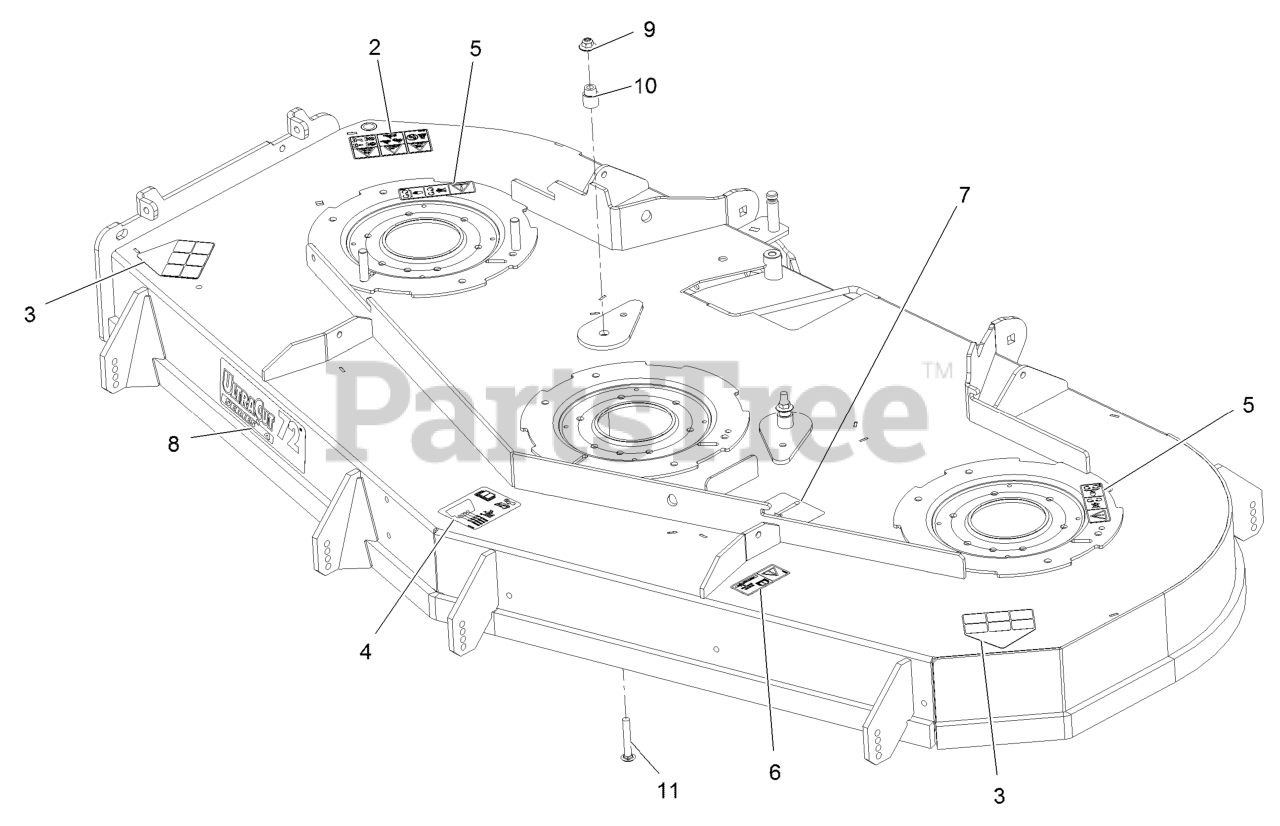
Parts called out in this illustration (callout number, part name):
2	DECAL-DANGER
3	DECAL-DANGER
4	DECAL-ROLLER, ANTI-SCALP
5	DECAL-COVER, MISSING
6	DECAL-BOLT TORQUE
7	DECAL-BELT ROUTING
8	DECAL,ULTRACUT 72 SERIES
9	Nut-Nyloc 3/8-16 Flg
10	BUSHING-IDLER
11	SCREW-CARR
